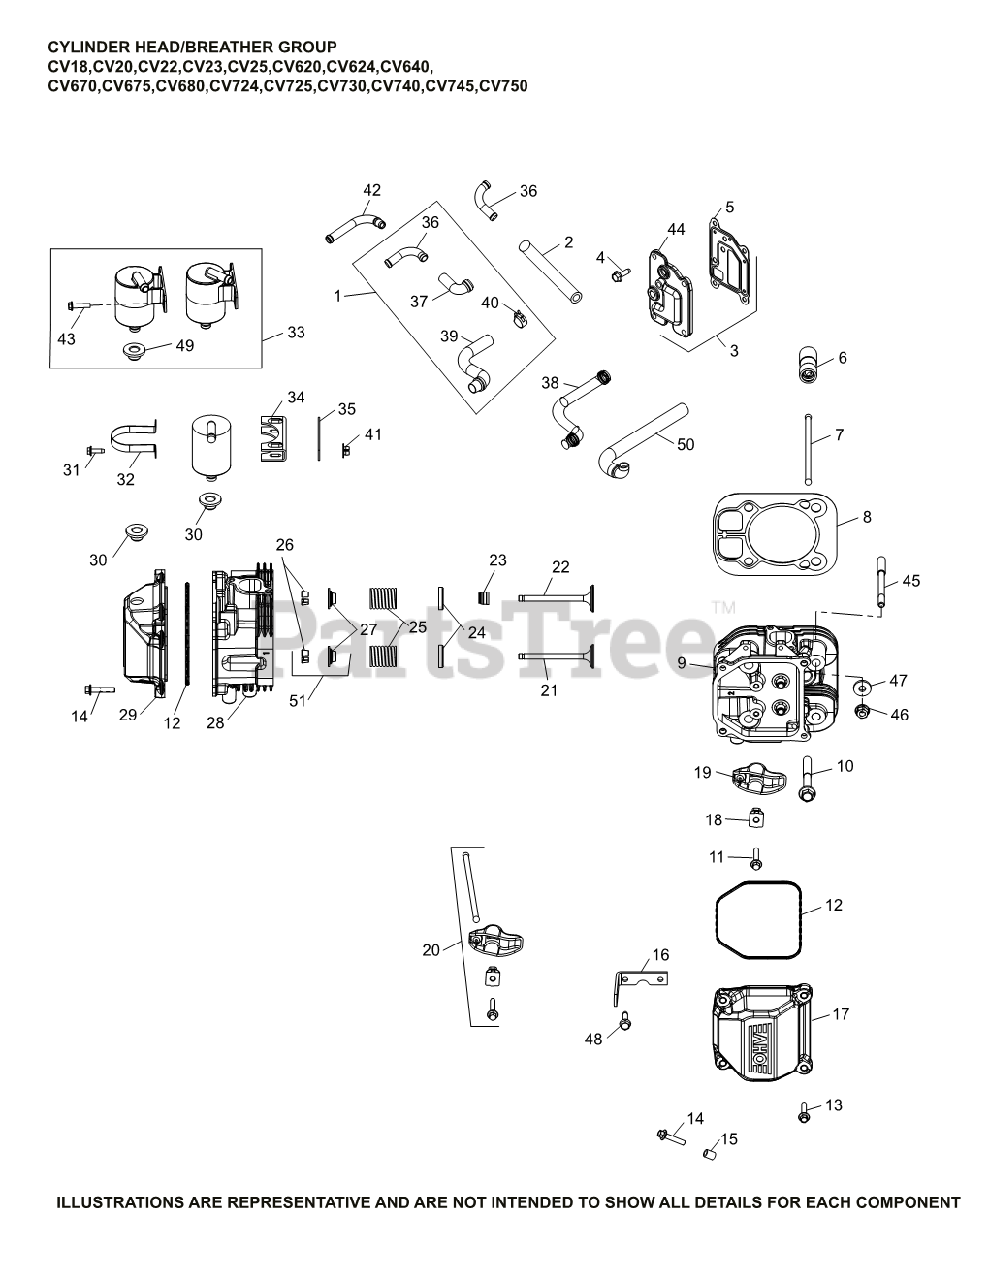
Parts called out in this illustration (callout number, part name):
4	SCREW, THREAD FORMING
5	GASKET, BREATHER
6	LIFTER, VALVE HYDRAULIC - (#2535111S)
7	ROD, PUSH
8	KIT, CYLINDER HEAD GASKET
9	KIT, #2 CYLINDER HEAD USE 24 318 172-S
11	SCREW, FLG M6X1.0X34
12	O-RING (YELLOW), VALVE COVER
14	SCREW, FLG M6X1.0X30
16	STRAP, LIFT
17	KIT, VALVE COVER-PLAIN
18	PIVOT, ROCKER ARM
19	ARM, ROCKER
20	KIT, VALVE TRAIN
21	VALVE, EXHAUST (STD) - USE 32 016 01-S
21	VALVE, EXHAUST (.25)
22	VALVE, INTAKE (STD)
22	VALVE, INTAKE (.25)
23	SEAL, VALVE BAND
24	RETAINER, SPRING
25	SPRING, VALVE
26	RETAINER, VALVE SPRING - USE 25 173 28-S
27	CAP, VALVE SPRING
28	KIT, #1 CYLINDER HEAD USE 24 318 171-S
29	KIT, VALVE COVER
33	KIT, BREATHER SEPARATOR
43	SCREW, HEX FLANGE HI-LO
44	KIT, BREATHER COVER
45	STUD, M8X1.25
46	NUT, FLG M8X1.25
47	WASHER, FLAT 8.6 MM
48	SCREW, THREAD FORMING
49	GROMMET, RUBBER
50	HOSE, BREATHER
51	KIT, RETAINER
